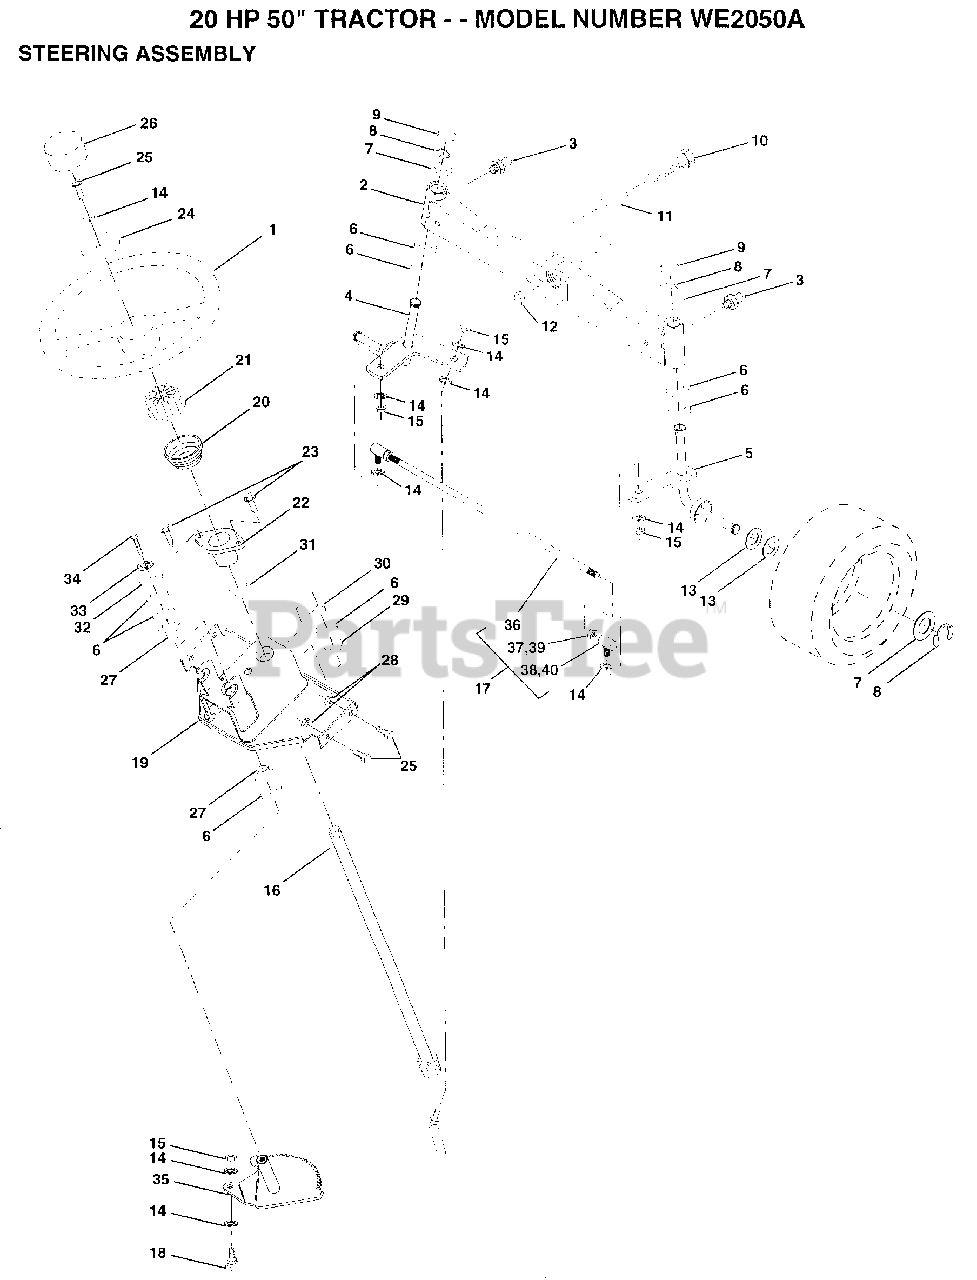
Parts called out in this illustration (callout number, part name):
3	ZERK M
4	SPINDLE.ASM.LH
6	WASHER .T
7	WASHER
8	RING
9	CAP
10	BOLT
11	SPACER BEARING
12	"NUT-LOC,FLANGE LT"
13	WASHER
14	LOCKWASHER
16	SHAFT ASSY GT
17	ROD.ASM.TIE.BALL
18	DRAGLINK.BALL.JOI
20	COLUMN STEERING
21	ADAPTER LT
24	WASHER T
25	BOLT
26	"INSERT,STR WHEEL"
27	COL. SRTG. BEAR.
28	NUT
29	"FLANGE GT, BEAR."
30	KLIP RING
31	BUSHING.NYLINER.
32	WASHER
33	LOCKWASHER
34	BOLT
35	GEAR.ASM.SECTOR.
37	NUT
38	JOINT.RH
39	NUT
40	JOINT.LH
